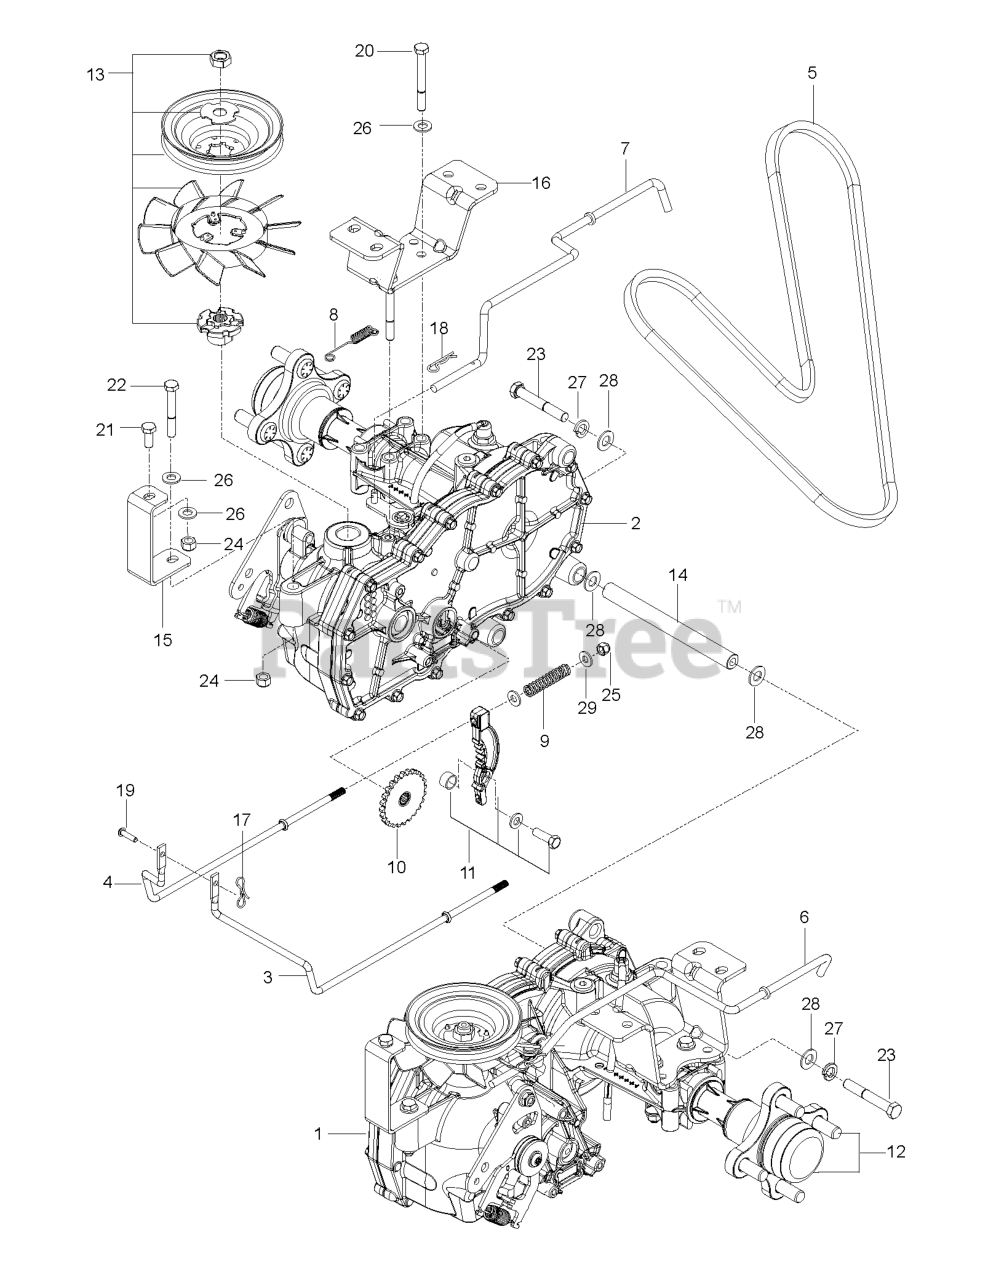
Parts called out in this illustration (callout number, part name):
1	HG_EZT, LT
2	HG_EZT, RT
3	LINKAGE.BRAKE.LT
4	LINKAGE, BRAKE RT
5	BELT, HYDRO PUMP
6	ROD.BYPASS.RZ.LH
7	ROD.BYPASS.RHT
8	SPRING.ROD.BYPASS.EZT
10	HG_DISC COG BRAKE 51635
11	HG_KIT BRAKE ARM (EZT)
12	HG_KIT, HYDRO-GEAR HUB
13	KIT FAN/PULLEY 72137
14	SPACER TUBE EZT
15	SUPPORT.FRONT.TRANS.PNTX431
16	BRACKET.EZT.MOUNT.REAR.PNTX431
17	PIN COTTER;LOCKING;BOWTIE;1IN
18	HAIRPIN #2
19	PIN.CLEVIS.3/16X.475
20	BOLT HEX
21	BOLT
22	BOLT.FIN HEX 5/16-18UNC X2 1/4
23	SCREW.HEX HEAD.38-16 X 2.5
24	NUT.71038.31-18.HEX.NYLOCK
25	LOCKNUT.NYLOC.1/4-20
26	WASHER
27	LOCKWASHER
28	WASHER
29	WASHER
